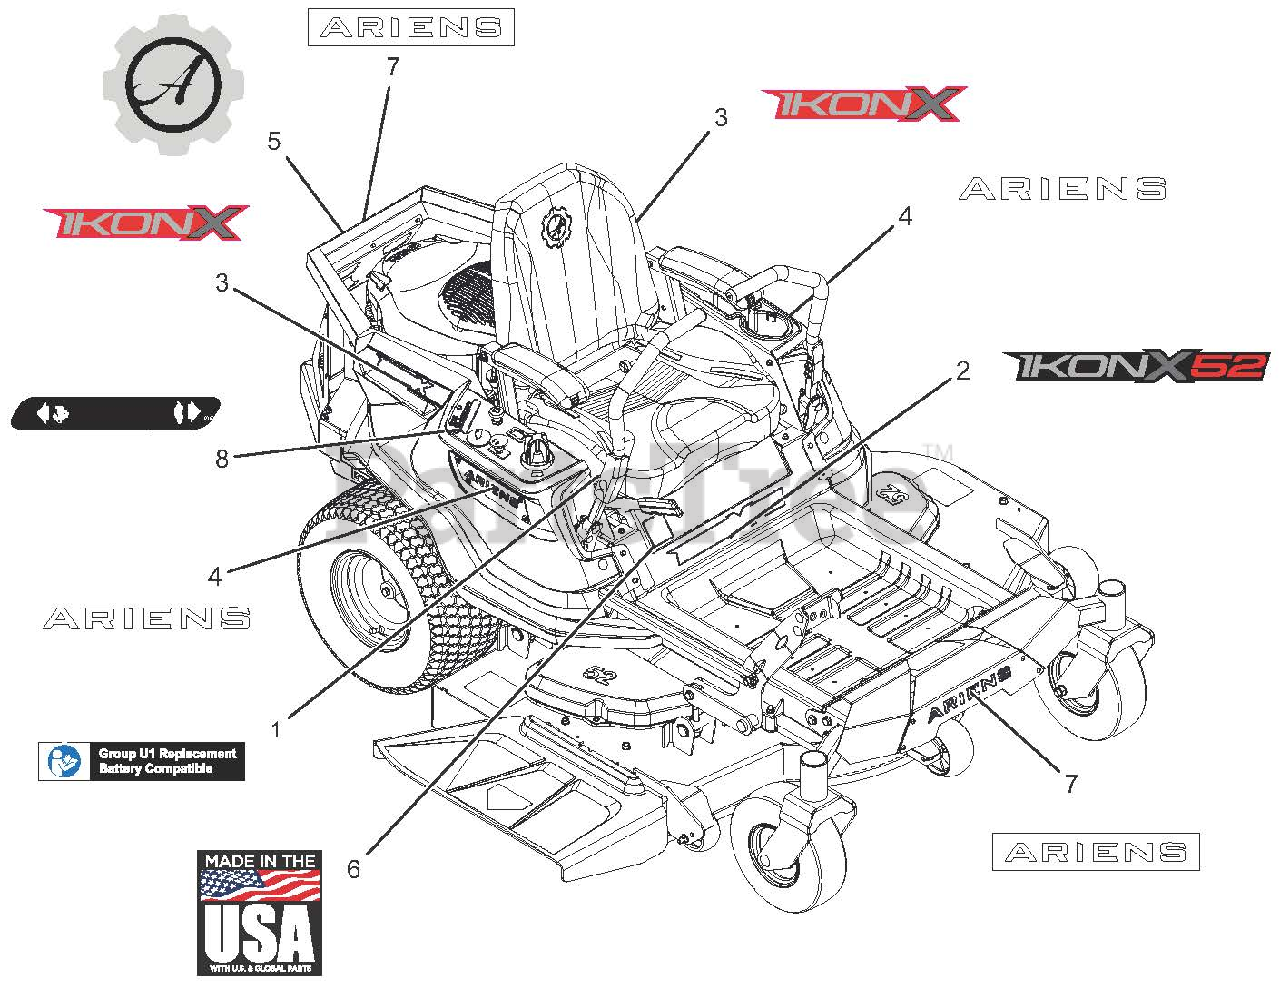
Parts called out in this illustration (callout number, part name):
1	DECAL, U1 BATTERY REPLACEMENT
2	DECAL, IKON-X 52"
3	DECAL, IKON
4	DECAL, ARIENS (6.50")
5	DECAL, ARIENS-GEAR BADGE
6	DECAL, MADE IN USA
7	DECAL - ARIENS 9.625"
8	DECAL, DASH DECAL
